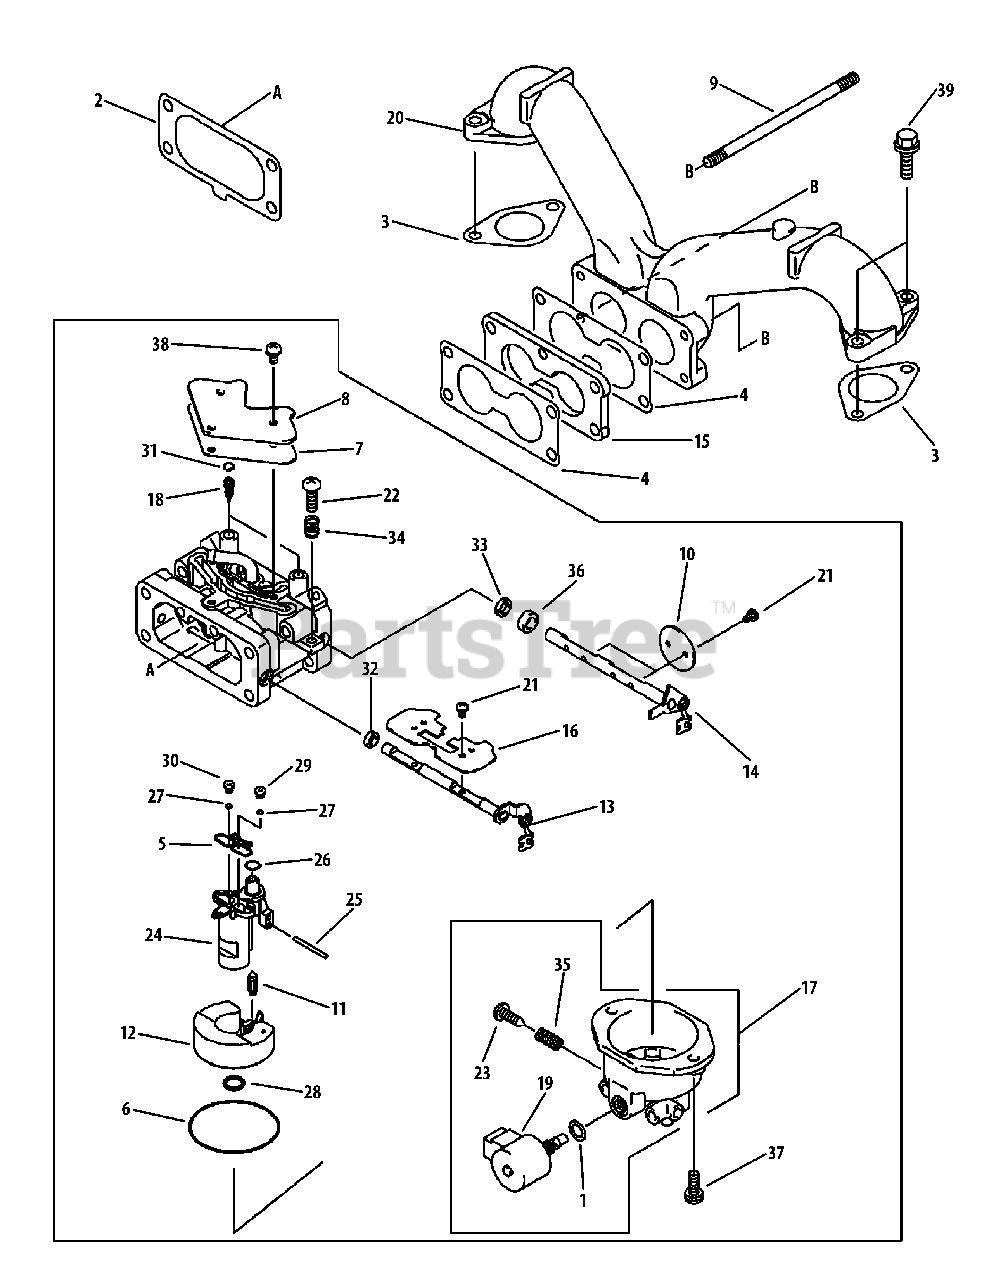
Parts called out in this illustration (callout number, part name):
2	Air Filter Gasket
3	Manifold Gasket
4	Carburetor Gasket
10	Throttle Valve
13	Carburetor Shaft
14	Carburetor Shaft
17	Float Chamber
20	Intake Manifold
26	O-Ring
29	Main Jet, #104
29	Main Jet, #101, 3280 FT
29	Main Jet, #098, 6560 FT
30	Main Jet, #102
30	Main Jet, #099, 3280 FT
30	Main Jet, #096, 6560 FT
31	Expansion Plug
32	D Seal Seal, 5.9
